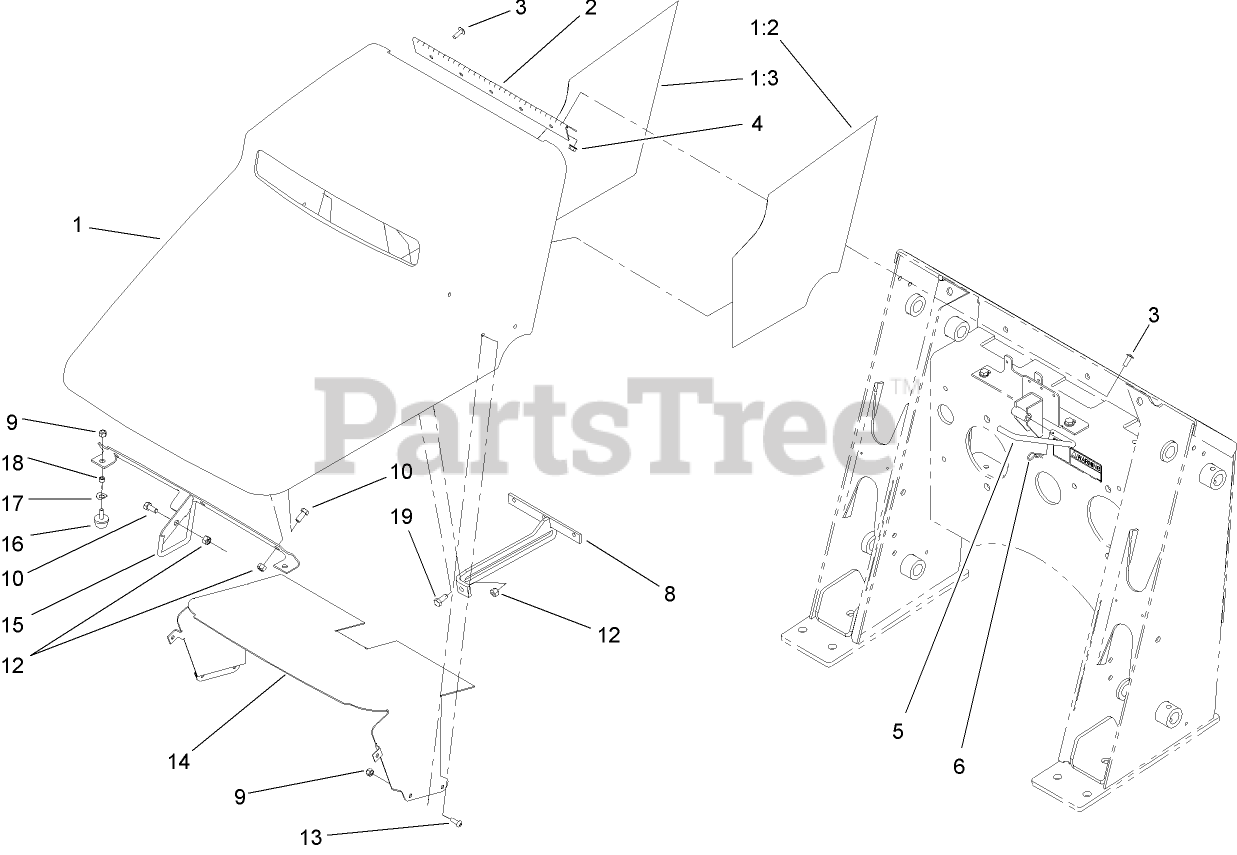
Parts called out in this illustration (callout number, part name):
1	HOOD ASM
1:2	FOILTAPE-LH
1:3	FOILTAPE-RH
2	HINGE-HOOD
3	SCREW-HEAD, TRUSS
4	NUT-HF
5	ROD-SUPPORT, HOOD
6	PIN-COTTER
8	PROP ROD BRACKET ASM
9	NUT-LOCK, NI
10	SCREW-HH
12	NUT-LOCK, NI
13	SCREW-PRH
14	BAFFLE-HOOD
15	ROD LATCH ASM
16	BUMPER
17	WASHER-SPRING
18	SPACER
19	SCREW-HH
